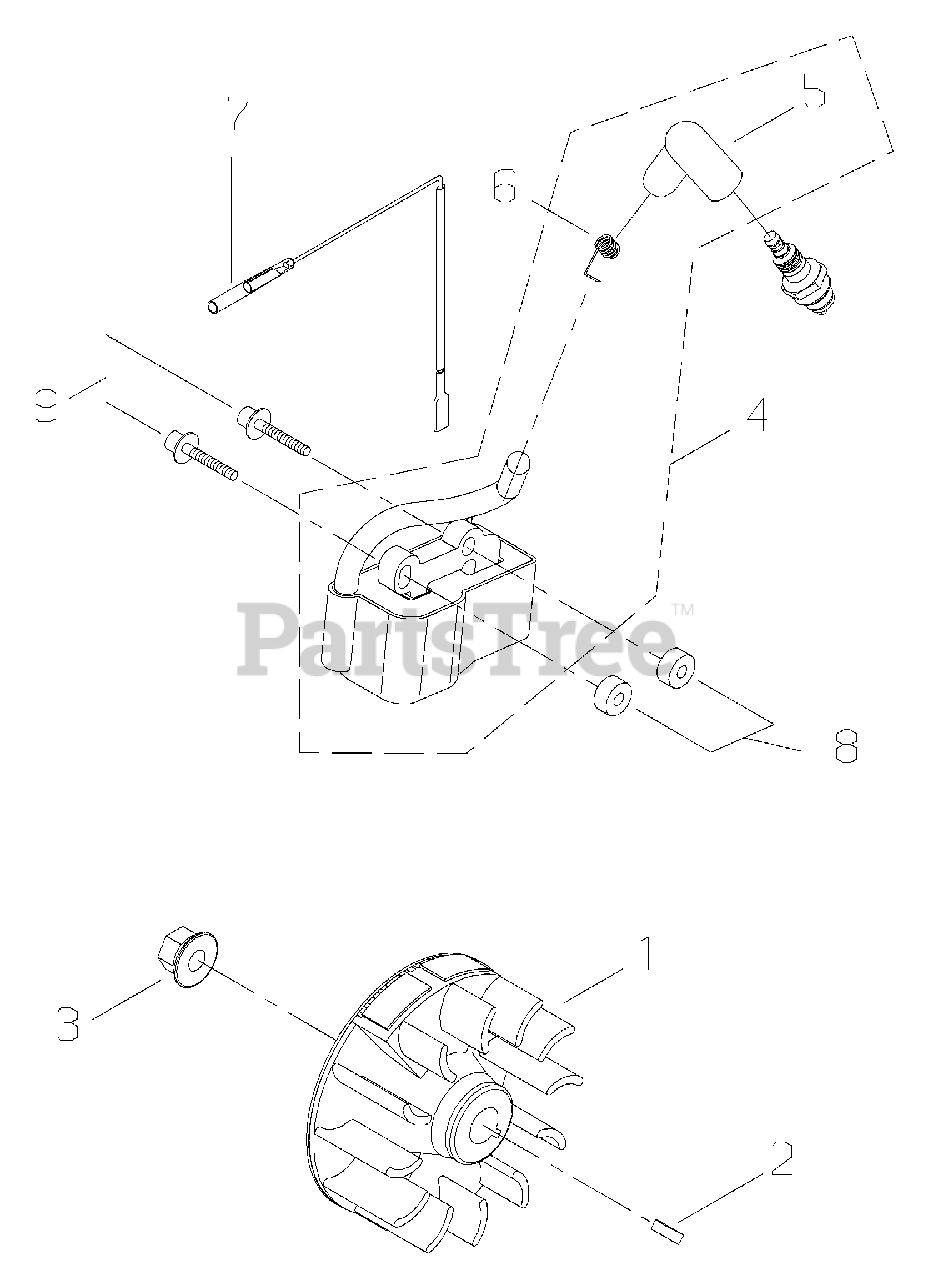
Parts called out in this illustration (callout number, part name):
1	FLYWHEEL
2	KEY, WOODRUFF 3×10
3	NUT M8
4	IGNITION COIL ASSY
5	CAP, SPARK PLUG
6	TERMINAL, SPARK PLUG
7	LEAD - IGNITION L= 220 MM
8	INSULATOR 4.2×11×6
9	BOLT M4×26
